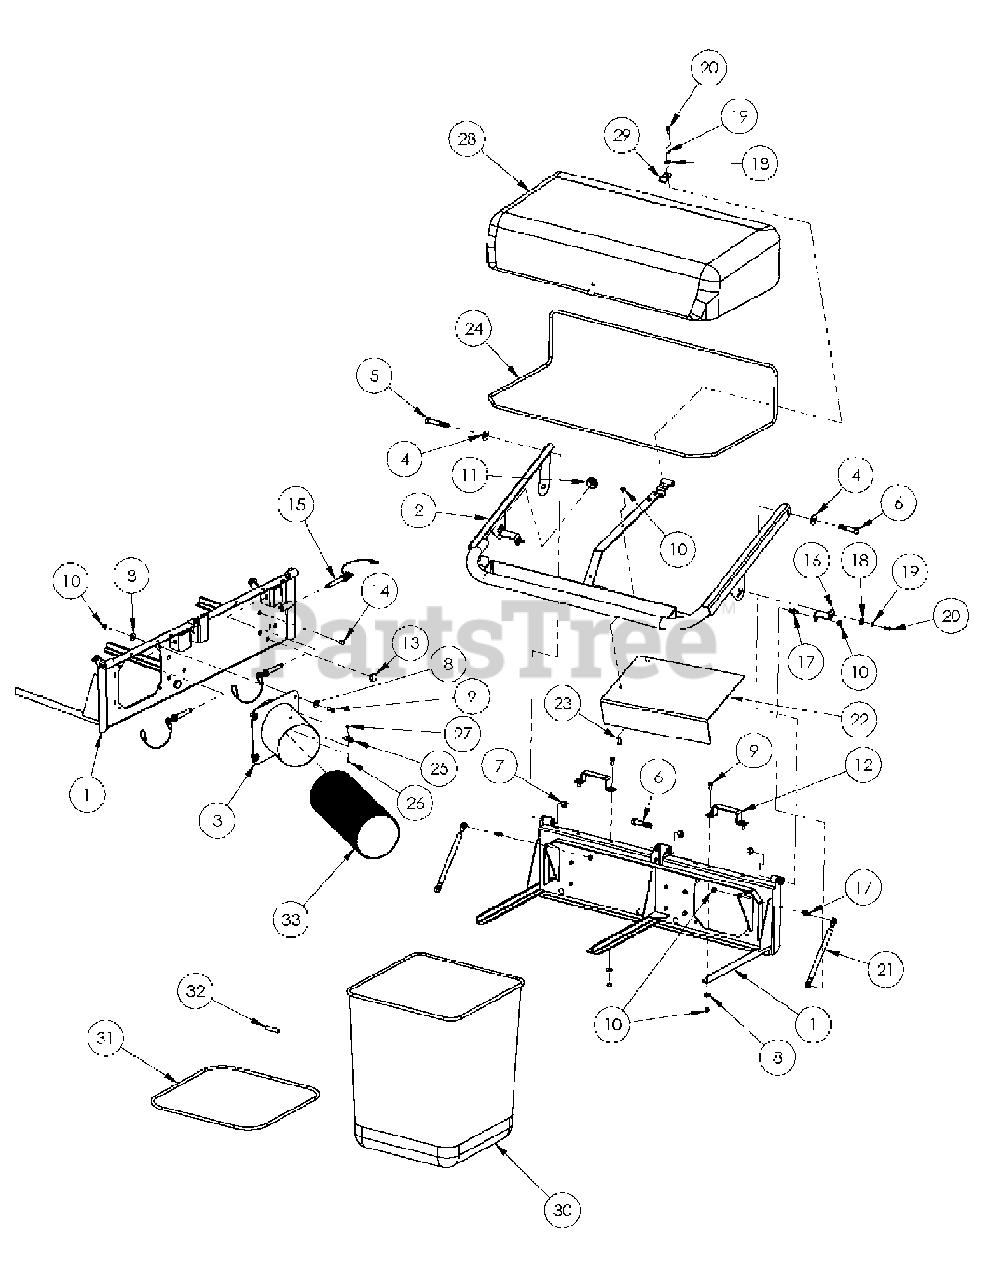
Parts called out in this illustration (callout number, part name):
1	2 BAG CATCHER BAG SUPPORT MOUNT
2	2 BAG CAP SUPPORT
3	INLET TUBE ASSEMBLY
4	FLAT WASHER-1/2
5	CAP SCREW-1/2"-13 X 3" LONG
6	CAP SCREW-1/2"-13 X 2 1/2" LONG
7	HEX NUT, NYLON INSERT-1/2"-13
8	FLAT WASHER-5/16"
9	CAP SCREW-5/16"-18 X 3/4" LONG
10	HEX NUT, NYLON INSERT-5/16-18
12	BAG HANDLE
13	RUBBER BUMPER
14	PLUG, HOLE 7/16
15	DETENT PIN W/ LANYARD-1/2" X 2 1/2" LONG
16	BRACKET-GAS CYLINDER MOUNT
17	BALL JOINT
18	1/4" WASHER
19	LOCK WASHER-1/4"
20	CAP SCREW-1/4-20 X 3/4" LONG
21	GAS CYLINDER
22	2 BAG DEFLECTOR
23	PAN HEAD SCREW-5/16"-18 X 3/4" LONG
24	AIR DOME FRAME, 2 BAG-3/8" ROD ONE PIECE
25	SPRING CLIP
26	MACHINE SCREW-#10-24 X 1/2" LONG
27	HEX NUT, NYLON INSERT-#10-24
28	2-BAG FABRIC CAP WITH "J" STRIP-PLAIN
29	BRACKET-SINGLE HOLE MOUNT
30	CATCHER BAG, COMMERICAL
31	GRASS BAG FRAME, COMMERCIAL
32	CONNECTOR TUBE
33	DISCHARGE HOSE
